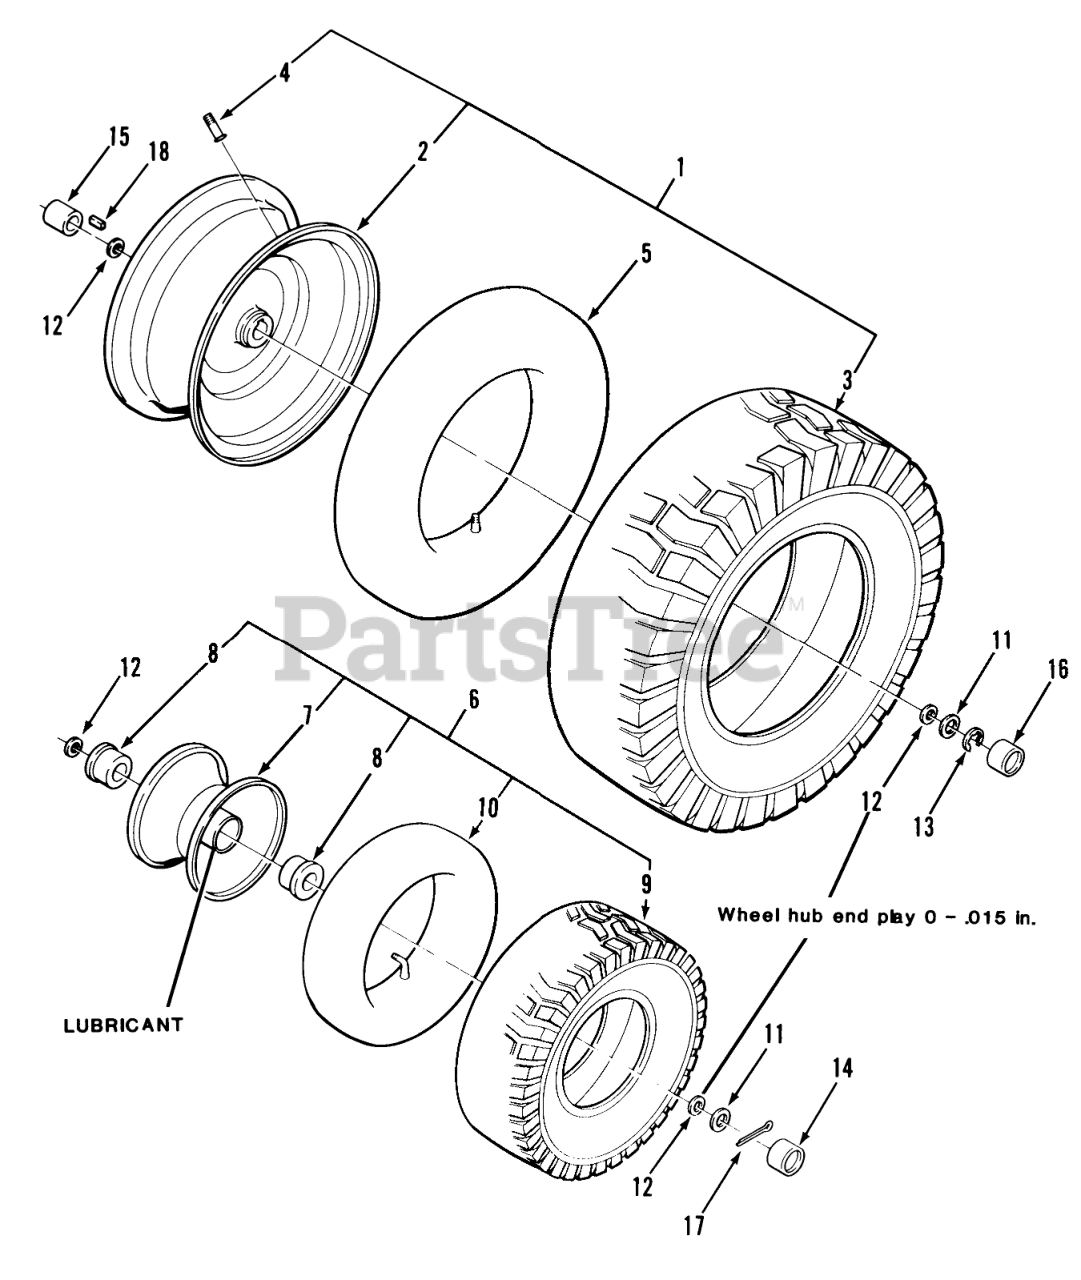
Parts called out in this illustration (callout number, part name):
1	Rear Wheel And Tire Assy
2	Rear Wheel
3	TIRE TURF SAVER 16X6.50-8
4	VALVE
5	TUBE-INNER
6	Front Wheel And Tire Assy
7	Front Wheel (Includes Bushings And Grease Fitting)
8	BEARING-WHEEL
9	TIRE TURF SAVER FT
11	WASHER-FLAT
12	WASHER
13	E Ring
14	HUB CAP-FLAT BLACK
15	LH AXLE SPACER
16	HUB CAP
17	Cotter Pin
18	SQ KEY
